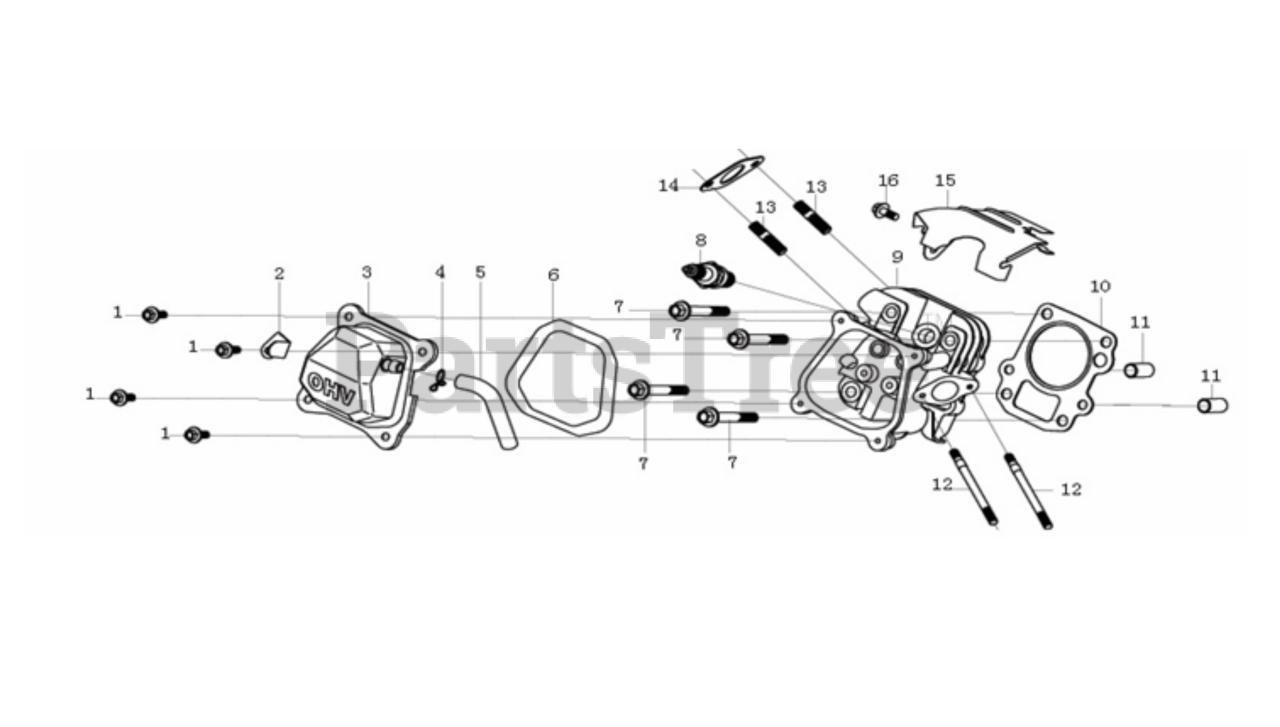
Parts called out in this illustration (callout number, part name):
1	Hexagon Bolt with Flange
2	Cable Cleat
3	Valve Cover Assembly
4	Pipe Clip
5	Breather Tube
6	Valve Cover Gasket
7	Hexagon Bolt with Flange
8	Spark Plug, Loncin 160CC
9	Cylinder Head
10	Head Gasket
11	Location Pin
14	Outlet Gasket
15	Air Deflector
16	Hexagon Bolt with Flange
